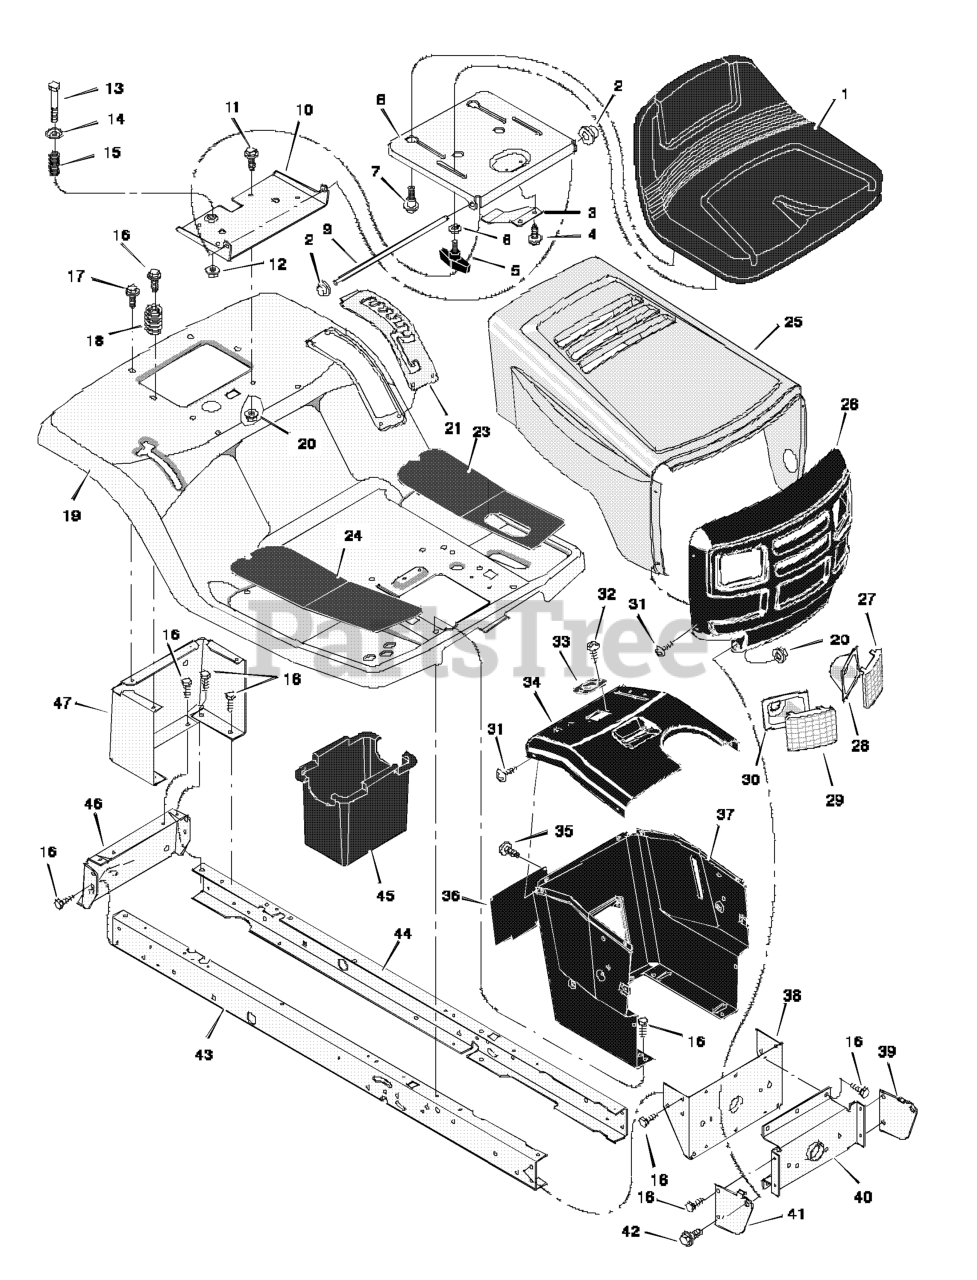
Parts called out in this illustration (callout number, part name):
2	Cap, Push On
5	Bolt, Wing
6	Washer
7	Bolt, Shoulder
8	Support, Seat
9	Rod, Pivot
10	Bracket, Pivot
11	Bolt
13	Bolt, Shoulder
15	Spring
19	Deck, Seat
20	Nut
21	Plate, Index
23	Mat, Left
24	Mat, Right
27	Lens, Left
28	Bezel, Left
29	Lens, Right
30	Bezel, Right
31	Screw
33	Bearing, Steering
35	Screw
36	Panel, Access
37	Support, Dash
38	Bracket, Rear Hanger
39	Support, Left Grille
40	Axle, Hanger
41	Support, Right Grille
42	Bolt, Shoulder
43	Frame, Right
44	Frame, Left
45	Container, Battery
46	Plate, Hitch
47	Panel, Rear
